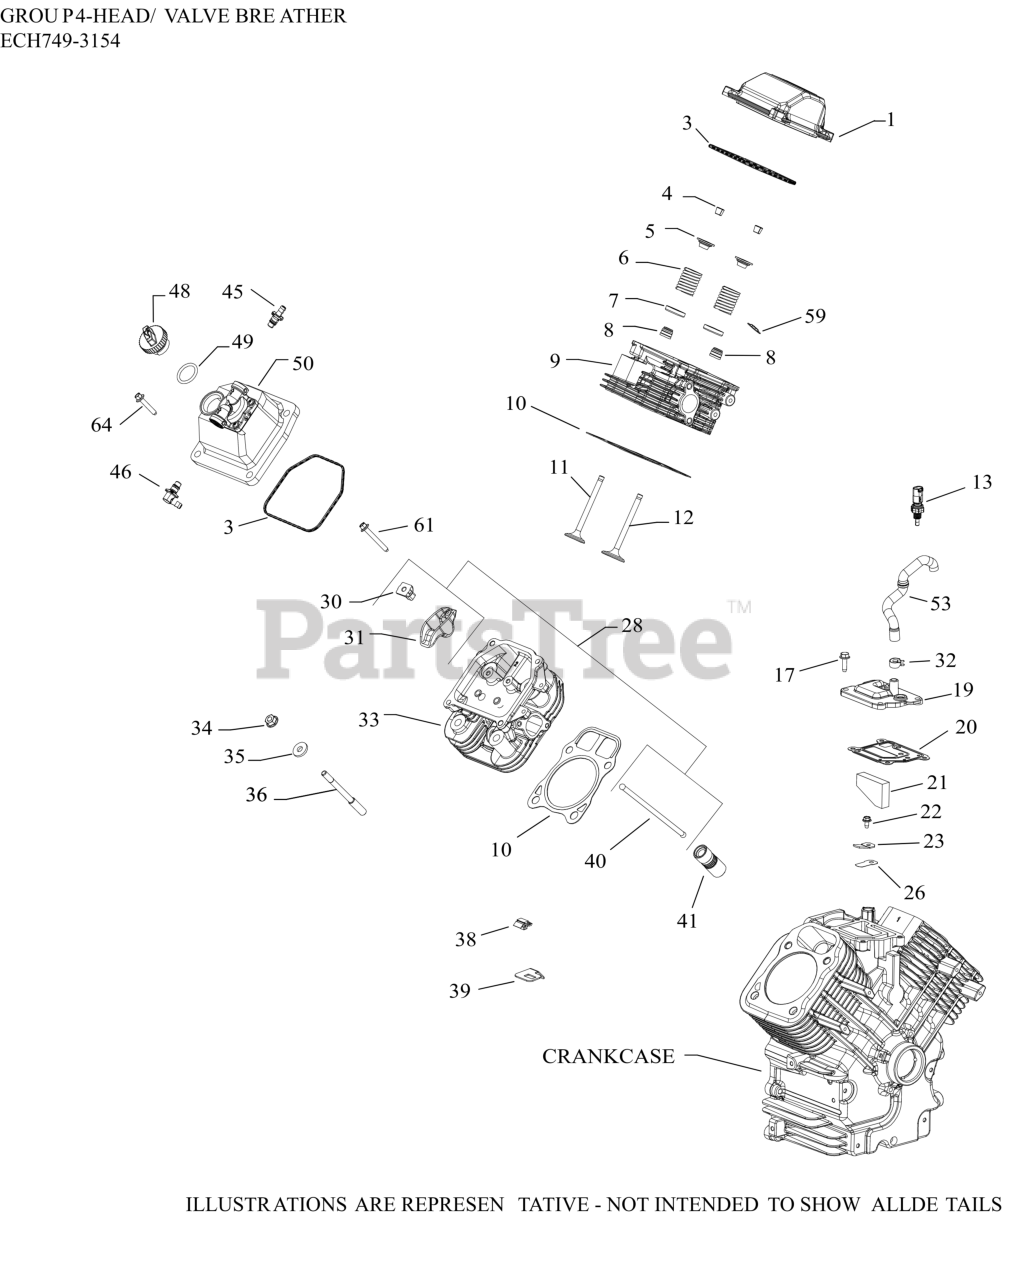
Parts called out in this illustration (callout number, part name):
1	KIT, VALVE COVER-PLAIN (PLASTIC)
3	O-RING (YELLOW), VALVE CO
4	KIT, RETAINER
5	CAP, VALVE SPRING
6	SPRING, VALVE
7	RETAINER, SPRING
8	SEAL, VALVE BAND
9	KIT, CYLINDER HEAD (#1)-(#2481803S)
10	KIT, GASKET CYLINDER HEAD
11	VALVE, EXHAUST
11	VALVE, EXHAUST (.25)
12	VALVE, INTAKE (STD)
12	VALVE, INTAKE (.25)-(#DSC)
13	SENSOR, TEMPERATURE
17	SCREW, THREAD FORMING
19	COVER, BREATHER
20	GASKET, BREATHER
21	FILTER, BREATHER
22	SCREW, FLG THD FRM M5X.8X10
23	RETAINER, REED
26	REED, BREATHER
28	KIT, VALVE TRAIN
30	PIVOT, ROCKER ARM
31	ARM, ROCKER
32	SPRING CLAMP, HOSE
33	KIT, CYLINDER HEAD (#2)-(#2481804S)
34	NUT, FLG M8X1.25
35	WASHER, FLAT 8.6 MM
36	STUD, M8X1.25
38	CLIP, O2 SENSOR
39	BRACKET, OXYGEN SENSOR
40	ROD, PUSH
41	LIFTER, VALVE HYDRAULIC-USE 25 351 11-S
45	KIT, STRAIGHT FITTING
46	KIT, 90 DEG. FITTING
48	CAP ASSY, OIL FILL (YELLOW)
50	KIT,VALVE COVER-FUEL PUMP
53	BREATHER, HOSE (EFI H/S, LPAC)
59	RETAINER, VALVE GUIDE (KM)
61	SCREW, HEX FLANGE
64	SCREW, HEX FLANGE (M6 X 31.625 DOG PT)
